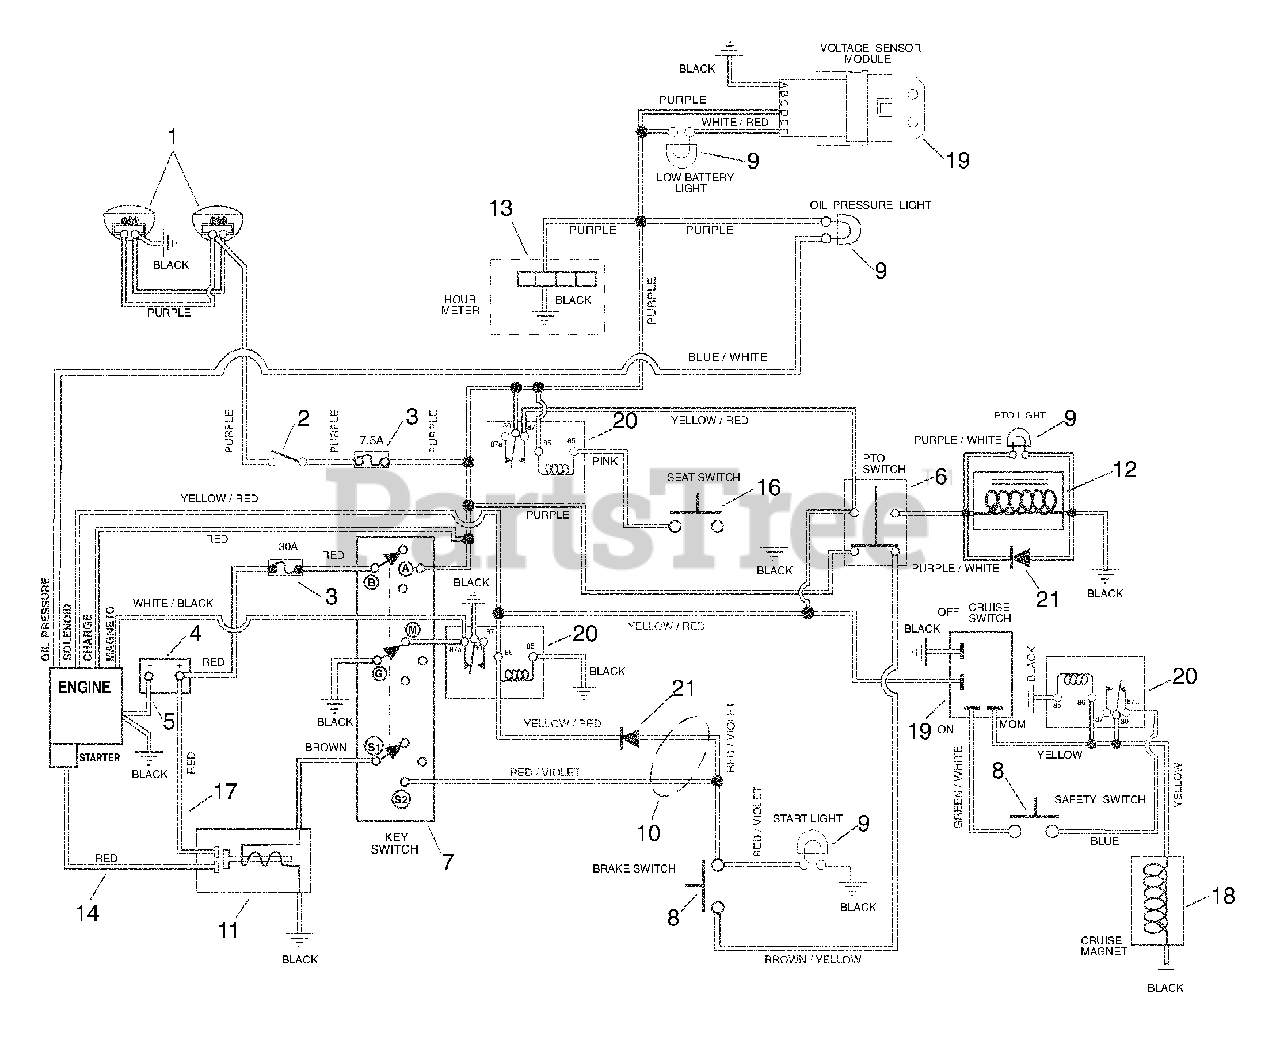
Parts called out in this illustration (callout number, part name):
1	HEADLIGHT- RH
1	HEADLIGHT- LH
2	SWITCH - LIGHT
3	7.5 AMP Fuse
3	30 AMP Fuse
4	BATTERY W/TUBE
5	GROUND CABLE .31X22.00X.31
6	PTO KNOB/ SWITCH ASSY
7	KEY SWITCH
8	SWITCH- SINGLE POLE N.O.
9	#194 Bulb
10	HARNESS, WIRING - 1640B&S TWIN
10	HARNESS, WIRING - 1648B&S TWIN
11	SOLENOID
12	ELECTRIC CLUTCH/BRAKE (3.4AMP)
12	CLUTCH, ELECTRIC - WARNER
13	HOURMETER KIT- SIERRA
14	START CABLE 22"
15	STARTER CABLE 6.75"
16	SWITCH- SEAT
17	SWITCH - CRUISE
19	MODULE - VOLTAGE SENSOR
20	RELAY
21	MOLDED DIODE PLUG 1 AMP
